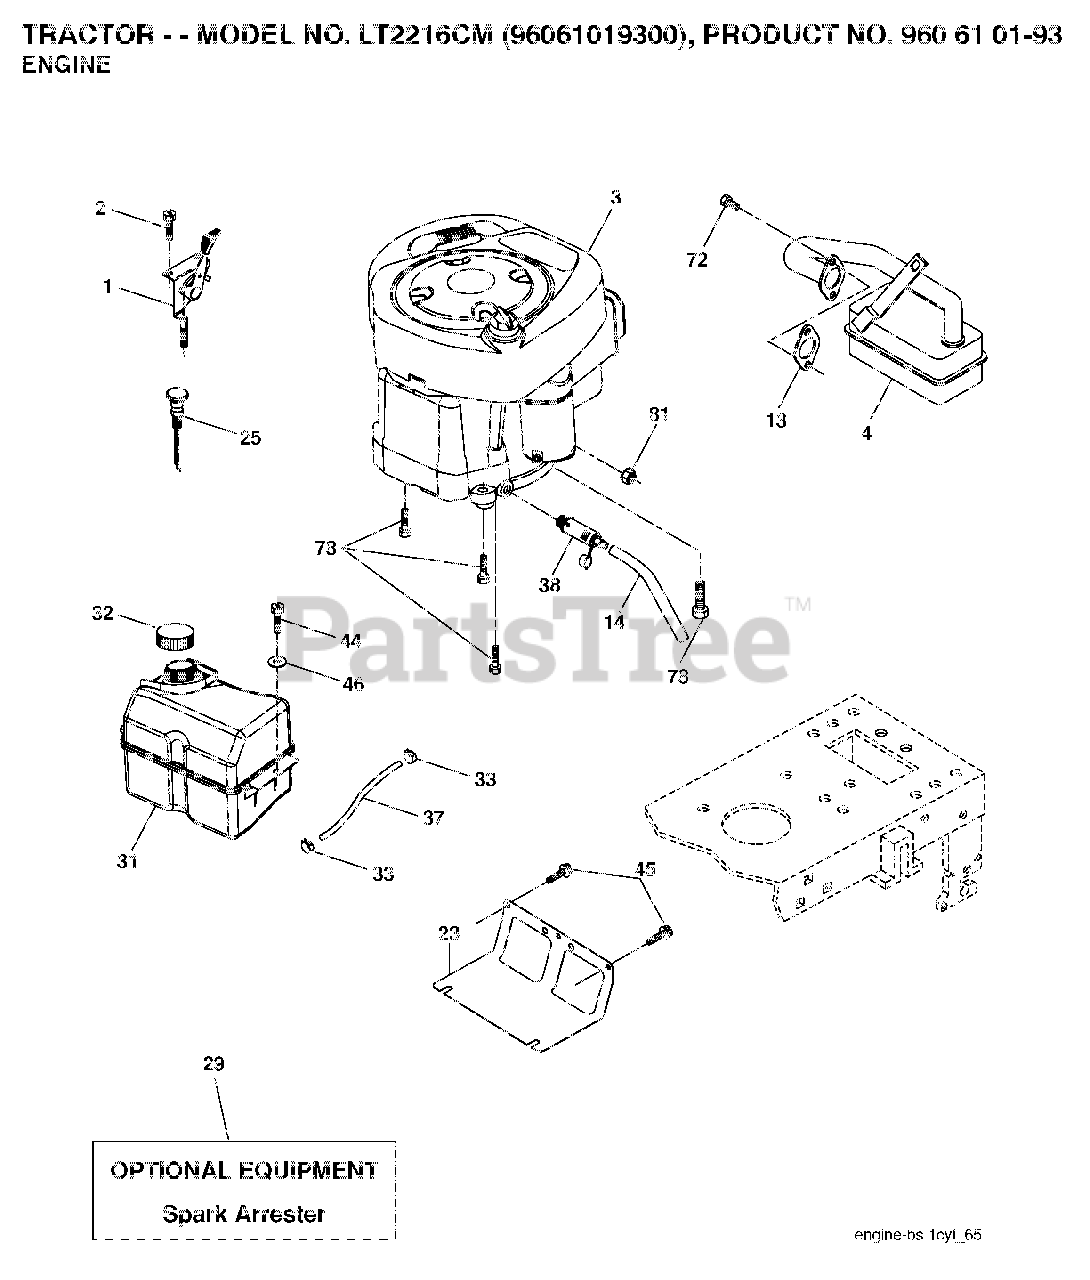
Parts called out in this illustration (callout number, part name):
1	CONTROL TH/CH FLAG
2	SCREW
13	REPL BY 532 27 22-93
14	TUBE, DRAIN OIL ASM.
23	SHEILD.BROWNING.DBR.GUARD
29	ARRESTER SPARK (OPTIONAL)
31	FUEL TANK FRT 2 GAL.
32	FUEL CAP
33	HOSE CLAMP
37	LINE.FUEL.20
38	PLUG DRAIN OIL EASY
44	SCREW HEXWSHR 1/4-20X3/4
45	SCREW, 3/8-16X3/4
46	WASHER
72	SCREW.SOCKET HD.5/16-1
78	SCREW.3/8-16
81	NUT
